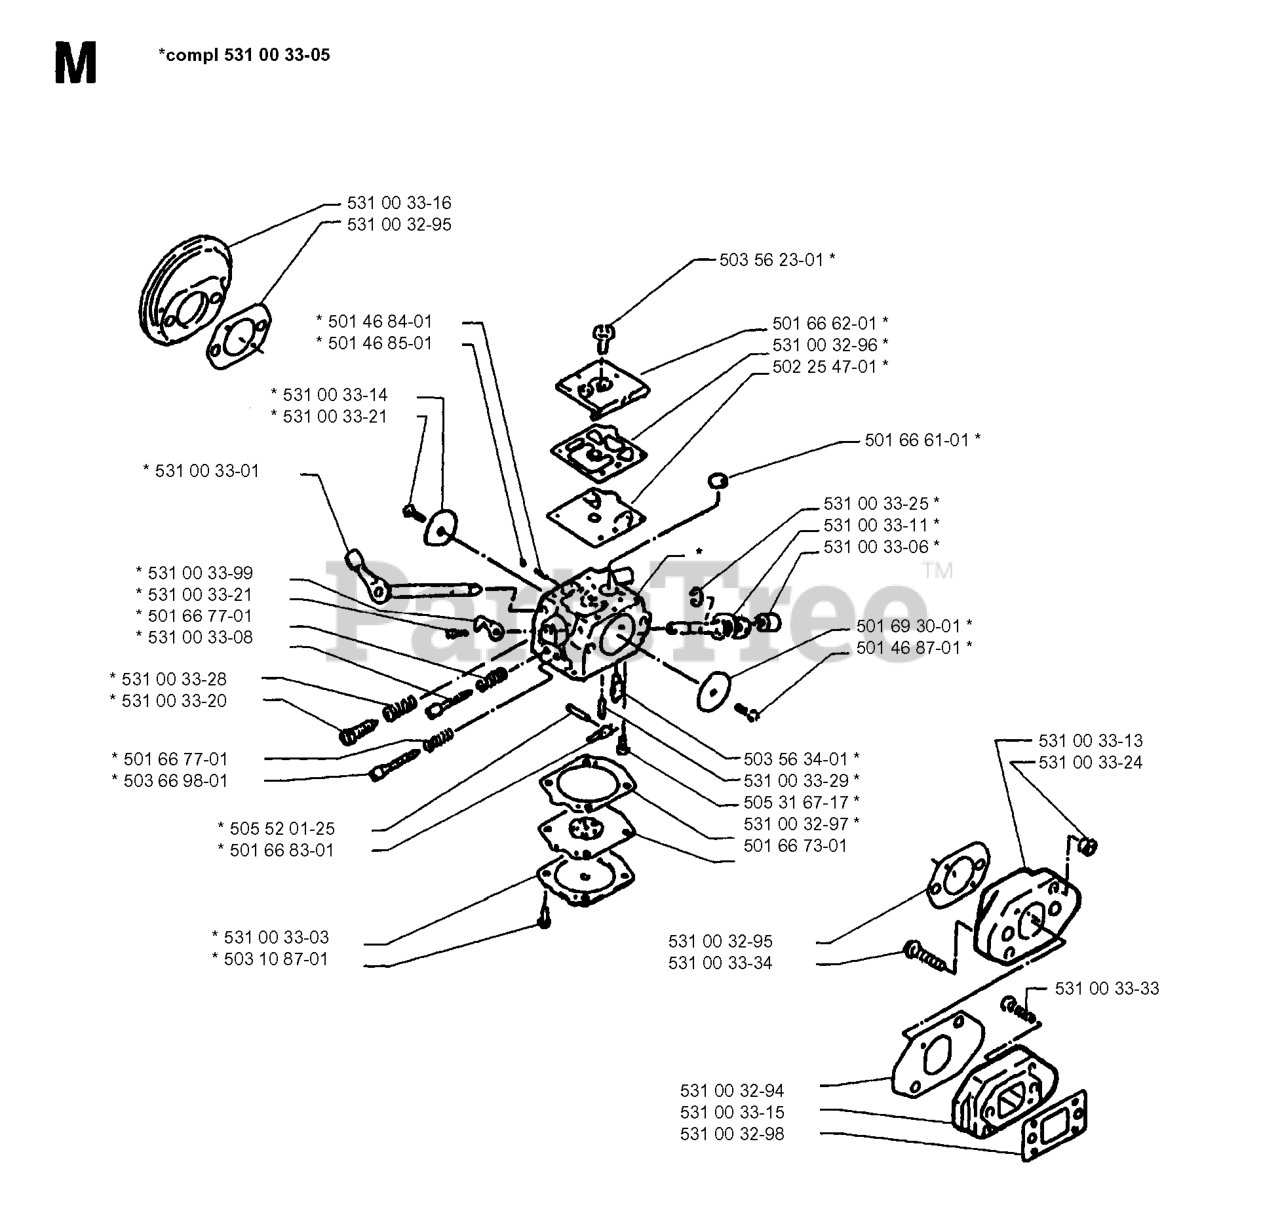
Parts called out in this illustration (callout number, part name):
2	KEY 1/4 X 2.5
5	NUT
6	PIN
7	HUB ASMBLY
9	BOLT HUB
15	NUT
17	SPRING.ROD.BRAKE
20	NUT
22	SHAFT ARM ASM
23	KNOB.DELUXE.(PISTOL.GRIP).BLAC
28	NUT
29	BRAKE ROD
30	WASHER
33	E RING HYT
34	PLUNGER CAP
35	ROD PARKING BRAKE
36	SPRING DRIVE GROUND
37	WASHER
39	SCREW FIN #10-24 X 1
40	ACT-SWITCH T
41	NUT TOPLOCK #10-24 X 1
42	PEDAL COVER T
46	RETAINER SPRING
47	CLUTCH ROD
48	BOLT
50	FLAT IDLER PULLEY
51	NUT LOCK HEX 3/8-16
52	PULLEY.IDLER.V.
54	CLUTCH.ARM.ASM.IDLER.98
55	BEARING LT (2 2)
61	PULLEY TRANSAXLE
64	SHAFT CLUTCH/BRAKE PEDAL
65	BOLT SHOULDER
66	WASHER.BLADE
67	BOLT
68	ROLL PIN STD
69	WASHER
70	FENDER CONSOLE
71	PLATE CONSOLE SHIFT
72	NUT
73	BOLT HEX FLGHD 5/16-18X 3 GR 5
74	SCREW, HEX WSH HI-LO 1/4-1/2
76	BRACKET TRANSAXLE
77	BOLT, FIN HEX 7/16-14 UNC X 1
79	BOLT CARRIAGE 5/16-18 X 5/8
80	TORQUE BRACKET RH
81	SCREW
82	BRACKET MOUNT TORQUE/FAN
83	STRAP TORQUE MID
85	SCREW #10-24 X 1-1/4
86	FAN 7" HYDRO
87	ADAPTOR.FAN.TRANSAXLE.VGTH
89	NUT, CROWNLOCK 7/16-14 UNC
90	KEEPER.BELT
91	SCREW THDROL 3/8-16 X 2-3/4
92	BOLT FIN HEX 5/16-18 X 1.75
93	LINK ASM SHIFT
94	FASTENER.XMAS.TREE
98	SHIFT BRACKET
99	SCREW 3/8-16 X 1-1/2
101	WASHER BELLVILLE
104	BRACKET IDLER
105	SCREW TAP 1/4-20 X 1/2
106	O-RING KIT 70110
107	LINE.VENT.HYDRO-GEAR
108	CAP, VENT ASSY
109	RETURN SPRING
111	SPACER SHIFT LEVER VGTH
112	WASHER NYLON HIGH TEMP
113	NUT HEX ASF 7/16-14 UNC
115	KEEPER BELT GND DR.
116	NUT LOCK HEX FLANGE 5/16-18
117	NUT LOCK FLG. 3/8-16 UNC
118	NUT LOCK HEX W/INS. 5/16-18UNC
